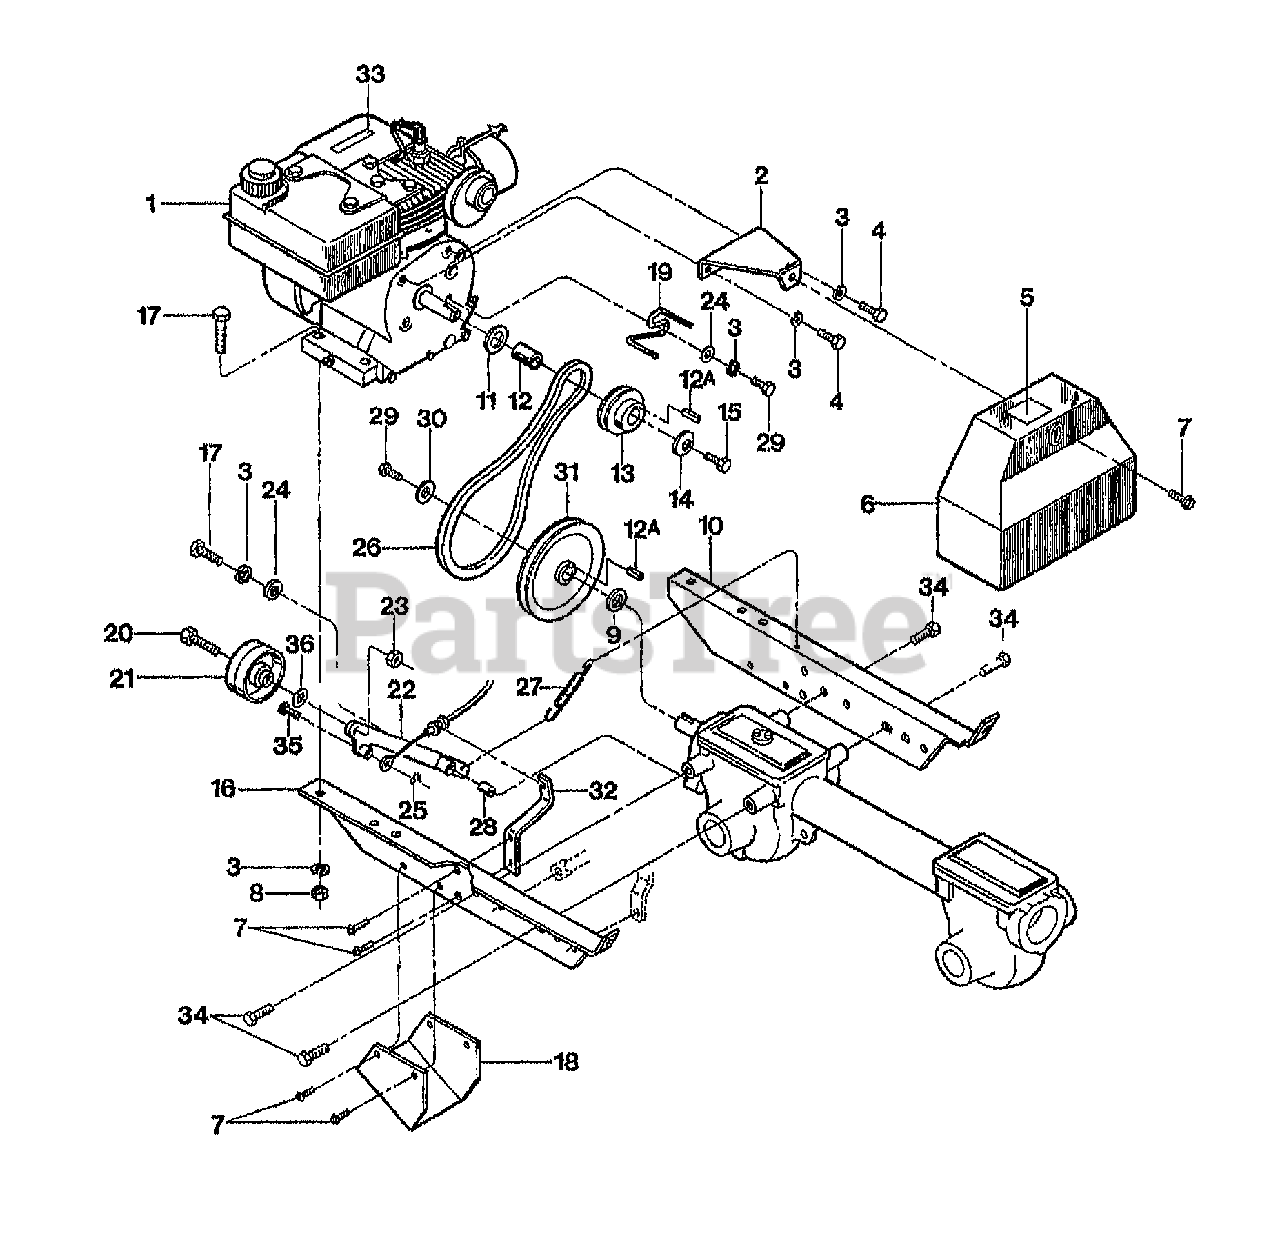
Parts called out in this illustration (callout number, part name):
1	ENGINE, TECUMSEH 3HP (H30-35387S)
2	BRKT-BELT COVER PNT
3	WASHER-LK .312 ZP
4	SCR-HH 5/16-24X.50
5	DECAL-HOT SURFACE
6	COVER-BELT W/DECAL 55053
7	SCR-HWH 1/4-20 X .5 STH
8	NUT-HEX 5/16-18 ZP
9	WASHER-SHLDR HARDENED
10	BRKT-ENGINE PNT
11	SHIM-1.0X.7656X.031
12	SPACER
12A	KEY-.188 SQX1.0
13	PULLEY-ENGINE
14	WASHER-.994X.413X.145
15	SCR-HH 3/8-24X1.0 G5 ZP
16	BRKT-ENGINE LEFT PNT
17	SCR-HH 5/16-18X1.5 G5 ZP
18	GUARD-BELT/PULLEY PNT
19	BELT STOP
20	BOLT-HH 3/8-16X1.5 FTH ZP
21	PULLEY-IDLER FORWARD
22	ARM-IDLER PNT
23	NUT-H/LK 3/8-16
24	WASHER-FLAT 5/16 SAE
25	RING-KLIP .188 DIA
26	BELT-V TUFFY
27	SPRING-RETURN
28	BUSHING-IDLER LEVER PM
29	SCR-HH 5/16-24X.75 G5 ZP
30	WASHER-.827X.331X.098
31	PULLEY-TRANSMISSION
32	BRKT-CABLE MTG PNT
33	DECAL-STARTING STABIL
34	SCR-HFLK 5/16-18X.62 G5ZP
35	PIN-CLEVIS CABLE
36	WASHER-FLAT 3/8 SAE
